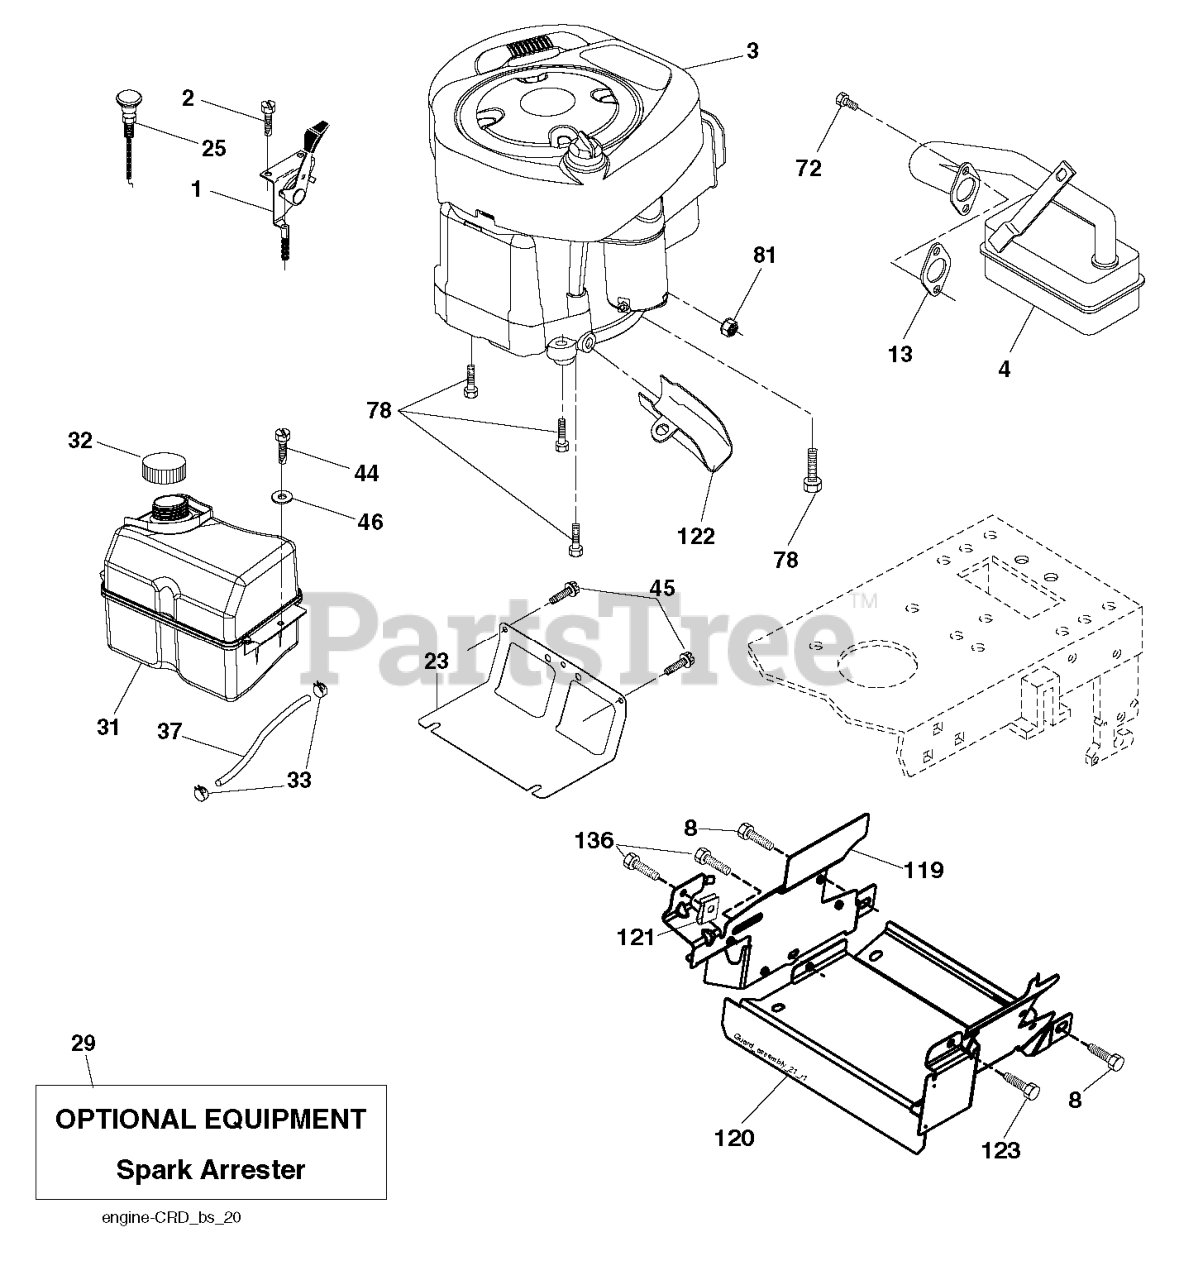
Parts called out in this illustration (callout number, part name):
1	CONTROL.THROTTLE/CHOKE.BLACK
2	SCREW
4	MUFFLER.LT.BRIGGS.14HP.IC/OHV
8	BOLT.5/16-18UNCX3/4 W/SEMS.BLK
13	REPL BY 532 27 22-93
23	SHIELD.BROWNING.DBR.GUARD
25	KNOB.ERGO.EXTENDED.RED (1 2)
29	KIT.SPARK ARRESTOR 794945 B&S
31	TANK.FUEL.FRT.N/CAP.2.0GAL.DAP
32	CAP ASM.FUEL.2.25"FR.
33	HOSE CLAMP
37	LINE.FUEL.20
44	SCREW HEXWSHR 1/4-20X3/4
45	SCREW, 3/8-16X3/4
46	WASHER
72	SCREW.SOCKET HD.5/16-1
78	SCREW.3/8-16
81	NUT
119	LENKRAD
120	GUARD 532199767
122	EXTENSION DRAIN OIL
123	SCREW, 5/16-18 X 1/2
136	SCREW.1/4-20X5/8
